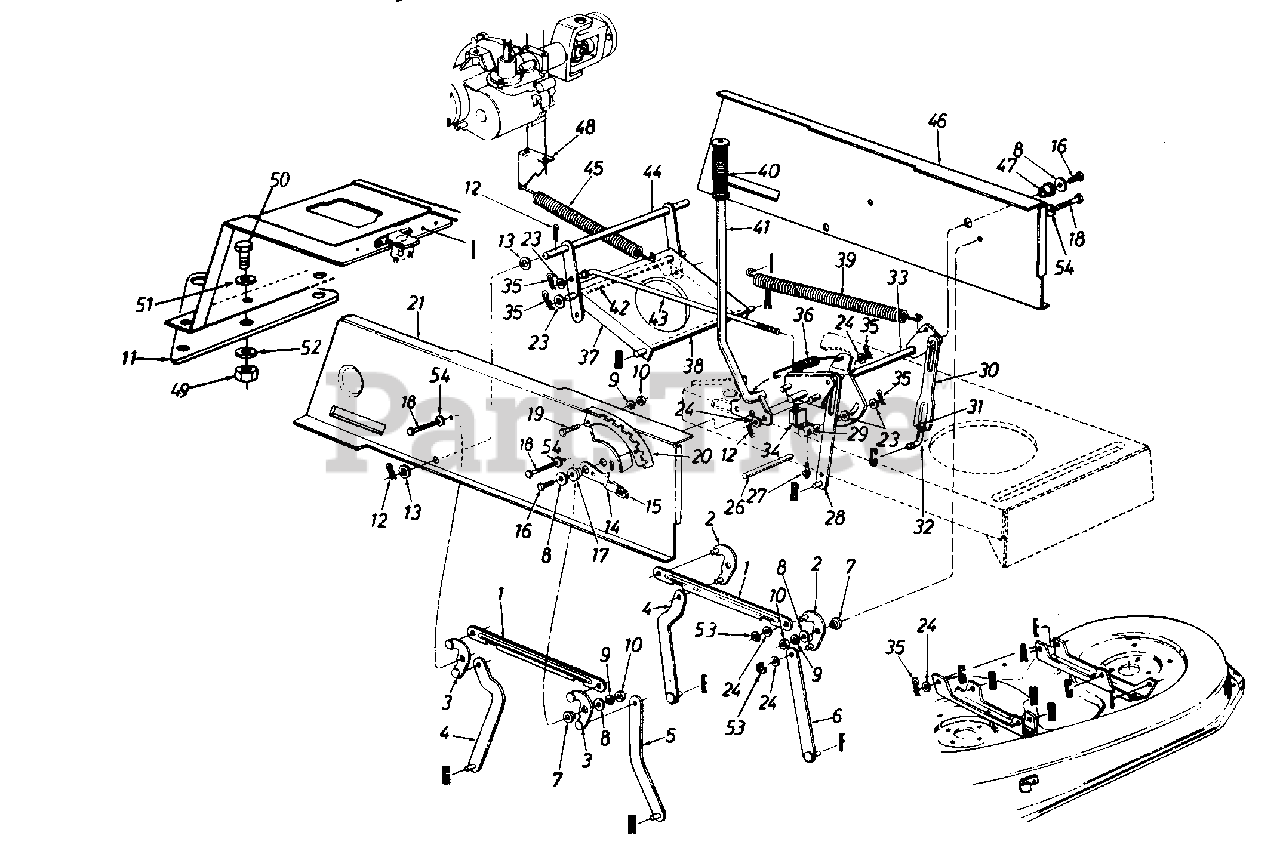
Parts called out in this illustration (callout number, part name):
3	Pivot Link Ass'y. - R.H.
7	Shld. Spacer .318" I.D.
8	Fl-Wash. .344" I.D. x 1.125"
9	L-Wash. 5/16" I.D.
10	Hex Nut 5/16-18 Thd.
11	Hitch Plate Extension
12	Cotter Pin 1/8" Dia.
13	Fl-Wash. .635" I.D. x 1.0" O.D.
14	Height Adj. Stop Lever Ass'y.
15	Knob
16	Hex Wash. TT-Tap Scr. 5/16-18 x .75" Lg.
17	Flange Brg. .63" I.D.
18	Hex Wash. Hd. Scr. 5/16-18 x .875" Lg.
19	Hex Bolt 5/16-18 x .75" Lg.
20	Index Brkt.
21	Upper Frame - R.H.
23	Fl-Wash. .385" I.D. x .87" O.D.
24	Fl-Wash. .531" I.D. x .93" O.D.
26	Running Board Rod
27	Truss Mach. Scr. #10 x .5" Lg.
31	Hex Nut 1/2-20 Thd. (Gr. 5)
32	Lift Link Adjuster
33	Lift Shaft Ass'y.
34	Safety Switch (Deck)
35	Inter. Cotter Pin 3/8" Dia.
36	Extension Spring
39	Extension Spring
40	Grip (Lift Handle)
41	Deck Lift Handle Ass'y.
42	Shaft 3/8" Dia. x 9.34" Lg.
43	Disengagement Rod
44	Stabilizer Shaft Ass'y.
45	Extension Spring 7.58" Lg.
46	Upper Frame - L.H.
47	Flange Brg. .632" I.D.
49	Hex Nut 7/16-14 Thd. (Gr. 5)
50	Hex Bolt 7/16-14 x 1" Lg.
51	Bell-Wash. .46" I.D.
52	Fl-Wash. .469" I.D. x 1.13" O.D.
53	"E"-Ring
54	Bell-Wash. .325" I.D.
